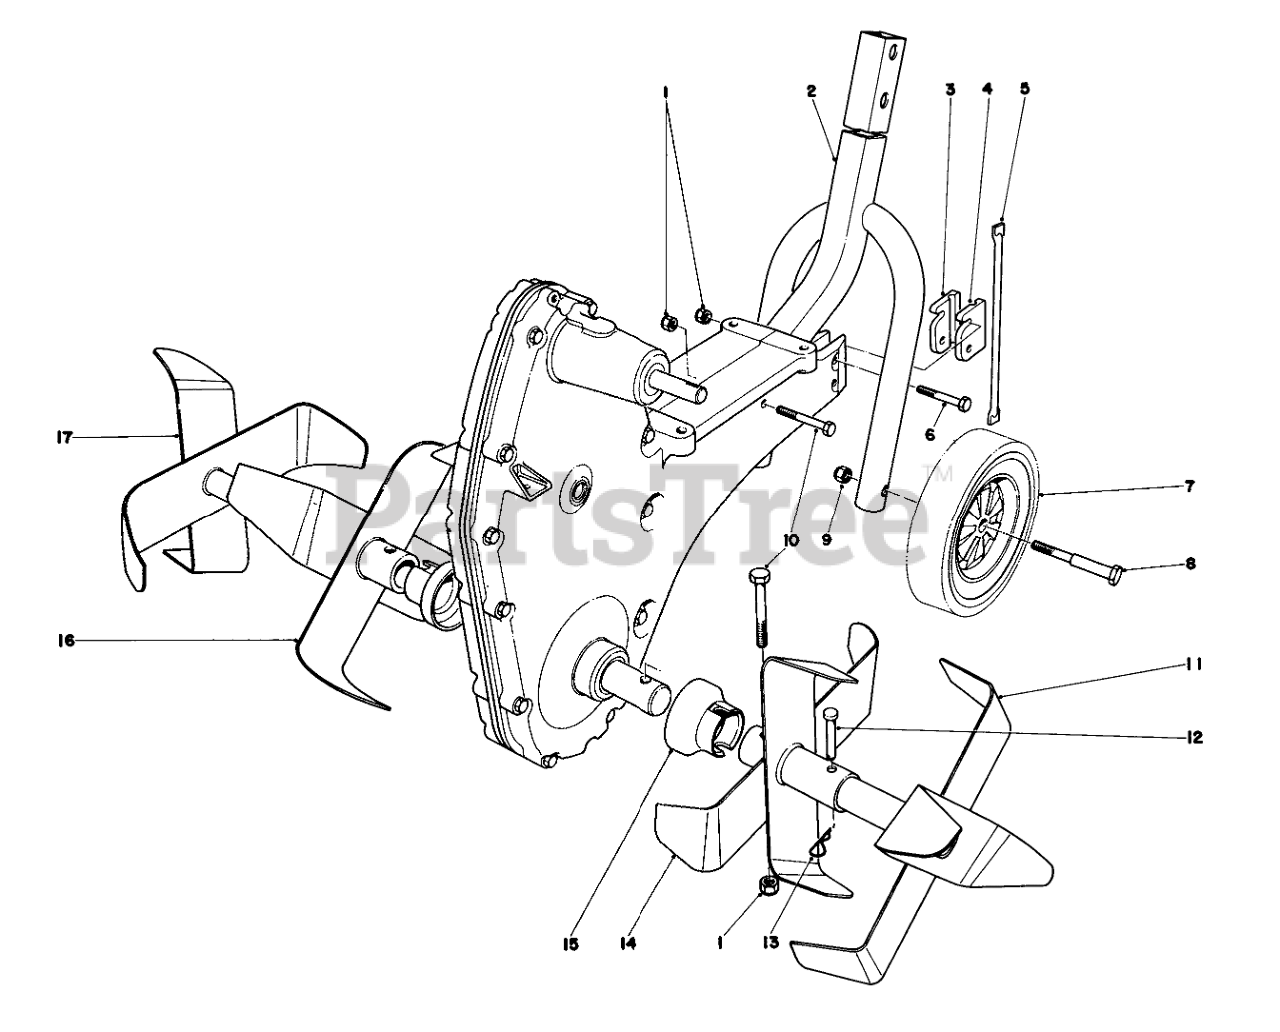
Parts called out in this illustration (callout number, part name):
1	NUT-HEX, SIDE DEFORM
2	Lower Handle
3	Pivot Block R.H.
4	LH PIVOT BLOCK
5	Drag Rod
6	SCREW-HH
7	WHEEL TIRE ASM 7 IN
8	Wheel Bolt
9	NUT-LOCK, CONE
10	SCREW-HH
11	Outboard Tine L.H.
12	CLEVIS
13	PIN-COTTER
14	Inboard Tine L.H.
15	Dust Cover
16	Inboard Tine R.H.
17	Outboard Tine R.H.
